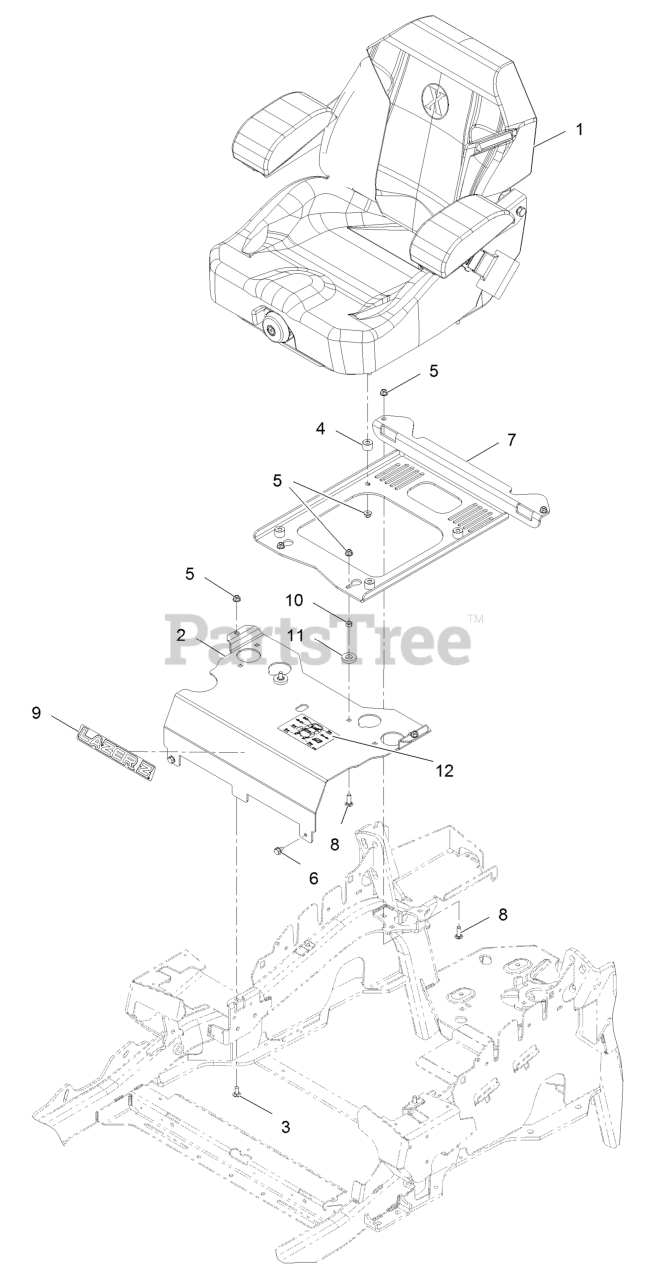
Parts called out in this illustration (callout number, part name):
1	KIT-SUSPENSION SEAT
2	MOUNT-SEAT
3	SCREW-CARR
5	NUT-HF, NI
7	PLATE-SUPPORT, SEAT
8	SCREW-CARR
9	DECAL, LAZER MODEL
10	NUT-HEX
12	DECAL-SERVICE AID
